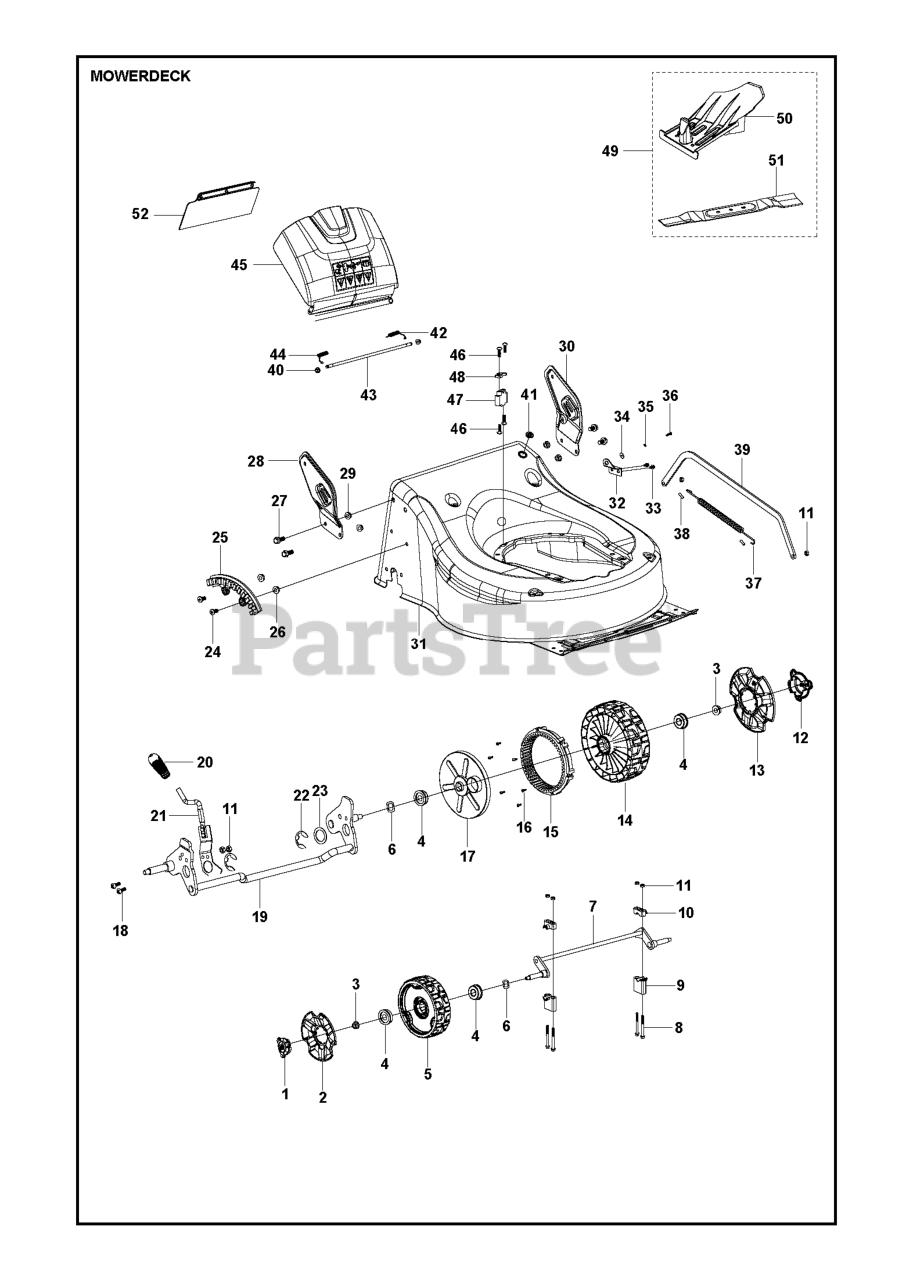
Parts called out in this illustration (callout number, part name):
1	WHEEL COVER 6" #25340700101
2	COVER 7 WHEEL COVER
3	LOCKING BOLT M8,GB6187.1 #2680
5	WHEEL ASSY 7 WHEEL
6	WASHER Ï?12 #26800706202
7	FRONT AXLE ASSY
11	LOCKING BOLT M6,GB889.1 #26800
12	WHEEL COVER 8" #25341000101
13	WHEEL COVER 8" #25341100101
14	WHEEL 8" #25341200101
15	GEAR WHEEL #25229900201
17	COVER #25342800101
18	WASHER M6*14 #26800203001
19	SHAFT ASSY REAR #26300298401
20	KNOB HEIGHT ADJUSTMENT #25341
21	HANDLE ASSY
22	WASHER Ï?19*1.5,GB896 #2680090
23	WASHER #26300107601
25	SEGMENT #25214200102
27	BOLT M8*16 #26800606401
28	BRACKET RH
30	BRACKET LEFT
31	CHASSIS # 21062009970013A
32	GUIDE PLATE # 26300360001
33	BOLT # 26800611201
34	WASHER # A26800700901
35	SPRING WASHER # A26800800402
36	SCREW TAPPING # A26800105402
37	SPRING #26801103903
38	TUBING #29000300101
39	CONNECTING ROD
40	LOCK NUT M6,GB/T6187.1-2000 #2
41	COVER #25217800104
42	BRACKET #26801125401
44	SPRING #26801125501
45	FLAP REAR # 2100X03758
47	HOLDER # 2109100010N
50	PLUG MULCHING
51	BLADE 26300349801
